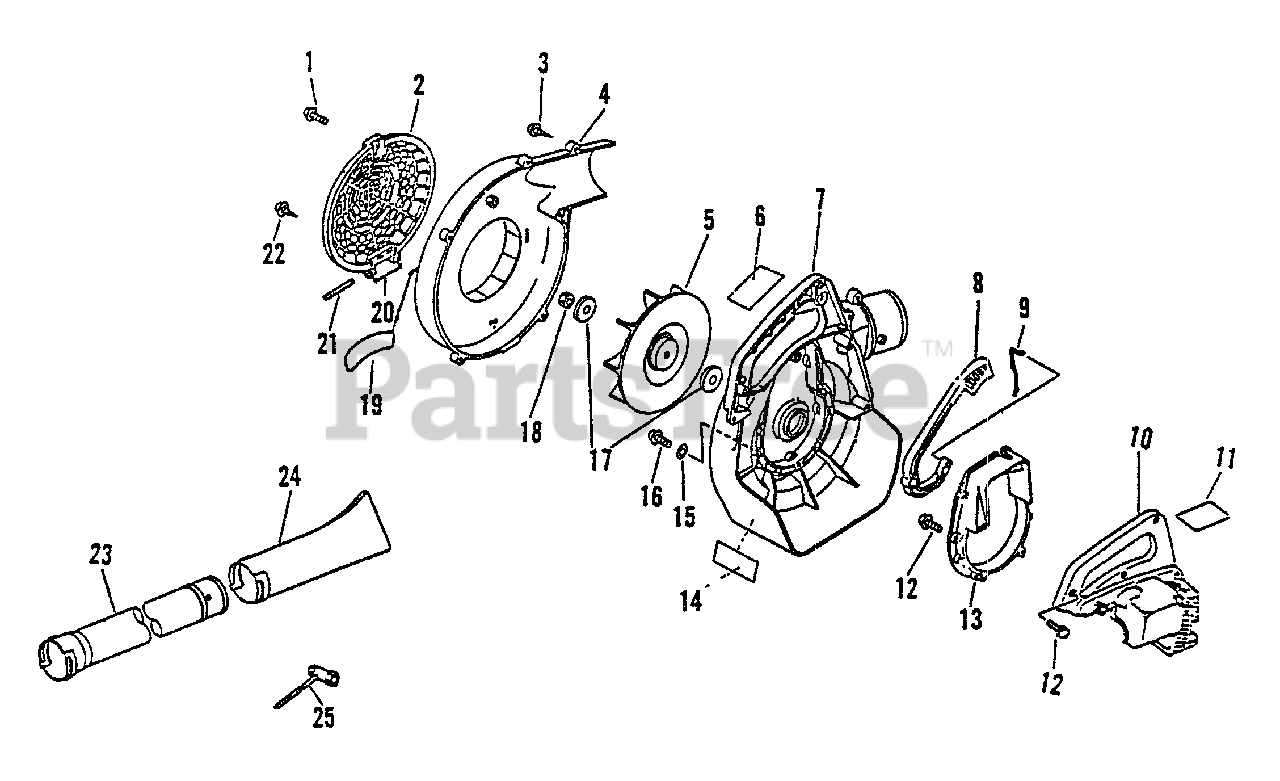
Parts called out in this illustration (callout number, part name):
1	SCREW 5×18
2	SHIELD, DEBRIS
3	SCREW, TAPPING 5×20
4	COVER, FAN - RIGHT
5	FAN
6	LABEL - NOISE
7	COVER, FAN - RIGHT
8	TRIGGER, THROTTLE
9	ROD, THROTTLE
10	COVER, ENGINE
11	LABEL - CAUTION -- HOT
12	SCREW 4×18
13	BRACKET, ENGINE
14	LABEL - CAUTION
16	SCREW 4×22
19	LABEL, LBH-2100
20	SPRING, COIL
21	PIN, INTAKE COVER
22	SCREW 5×14
23	TUBE, BLOWER - STRAIGHT
24	NOZZLE - FAN HEAD
25	T-WRENCH 13×19×180
